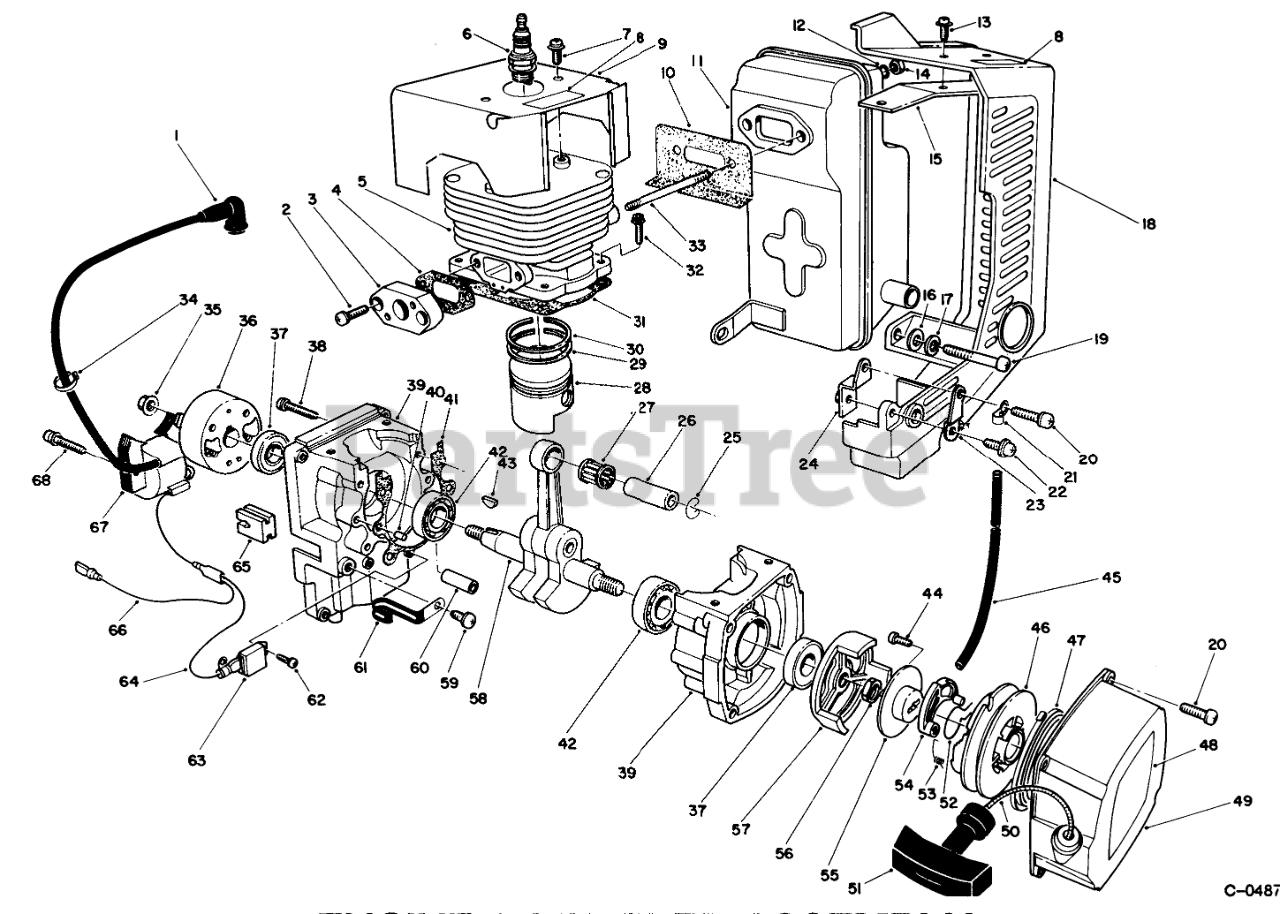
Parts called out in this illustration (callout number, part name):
1	CAP-PLUG
2	SCREW & WASHER
3	FLANGE
4	GASKET
5	CYLINDER
6	SPARK PLUG
7	SCREW & WASHER
8	DECAL-SURFACE, HOT
9	CYL COVER
10	MUFFLER GASKET
11	MUFFLER
12	Washer-Lock
13	SCREW & WASHER
15	BRACKET
16	Washer
17	Washer-Lock
18	MUFFLER COVER
19	Screw
20	SCREW & WASHER
21	Clamp
22	SCREW & WASHER
23	BRACKET
24	BRACKET
25	PISTON PIN CLIP
26	PISTON PIN
27	NEEDLE BEARING
28	Piston (Incl. Ref. #26)
29	TOP RING
30	TOP RING
31	GASKET
32	FLANGE BOLT
33	STUD BOLT
36	ROTOR
37	OIL SEAL
38	SCREW & WASHER
39	Crankcase Assembly (Incl. Ref. #38, 40)
40	Knock Pin
41	GASKET
42	BALL BEARING
43	Key-Woodruff
44	Screw
45	FUEL TUBE
46	Reel
47	Spring
48	DECAL
49	Case-Starter
50	STARTER ROPE
51	STARTER KNOB
52	SPRING, FRICTION
53	SPRING, RETURN
54	Ratchet
55	FRICTION PLATE
56	J/S NUT
57	STARTER PULLEY
58	Crankshaft
59	Screw
61	Clamp
62	SCREW W/ WASHER
63	TRANSISTER UNIT
64	LEAD WIRE
65	Grommet
66	WIRE LEAD
67	IGNITION COIL
68	BOLT AND WASHER
